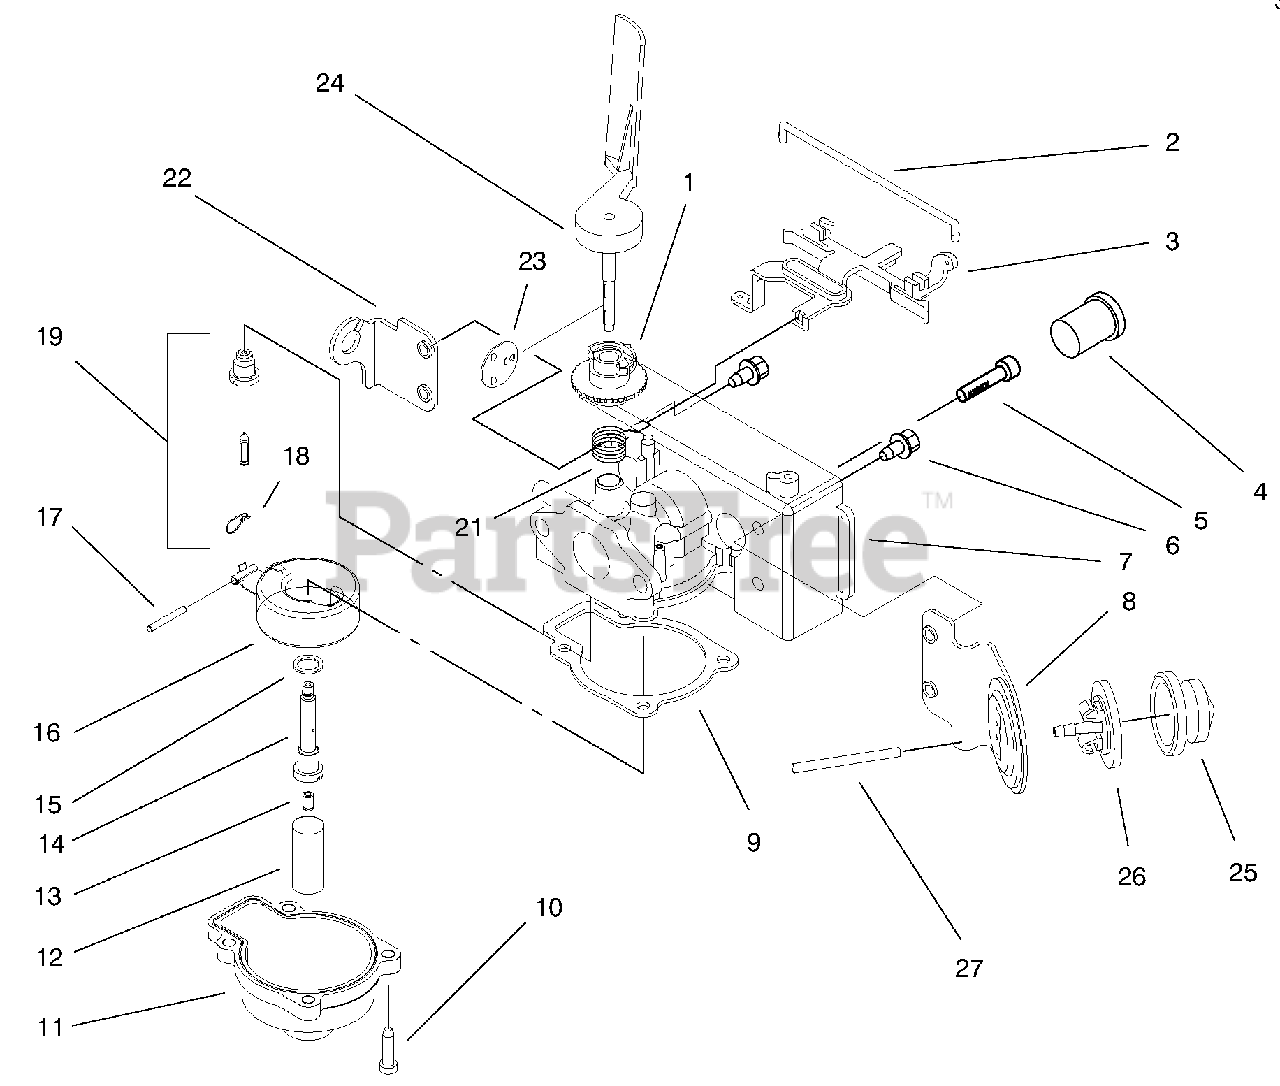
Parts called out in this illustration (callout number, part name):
1	Collar-Adjustment
2	Retainer
3	Lever-Speed Adjust
4	Plug
5	Screw-Pan Hd. Sems
7	Body-Carburetor
8	Bracket-Primer
9	Gasket-Float Chamber
11	Float Chamber
12	Filter-Fuel
13	Main Jet
16	Float & Arm Assembly
18	Clip
19	Float, Valve, & Body Ass'y
21	Spring-Governor
22	Bracket-Throttle Control
23	Disc-Throttle
24	Air Vane & Shaft
25	Bulb-Primer
26	Body-Primer
27	Hose-Primer
